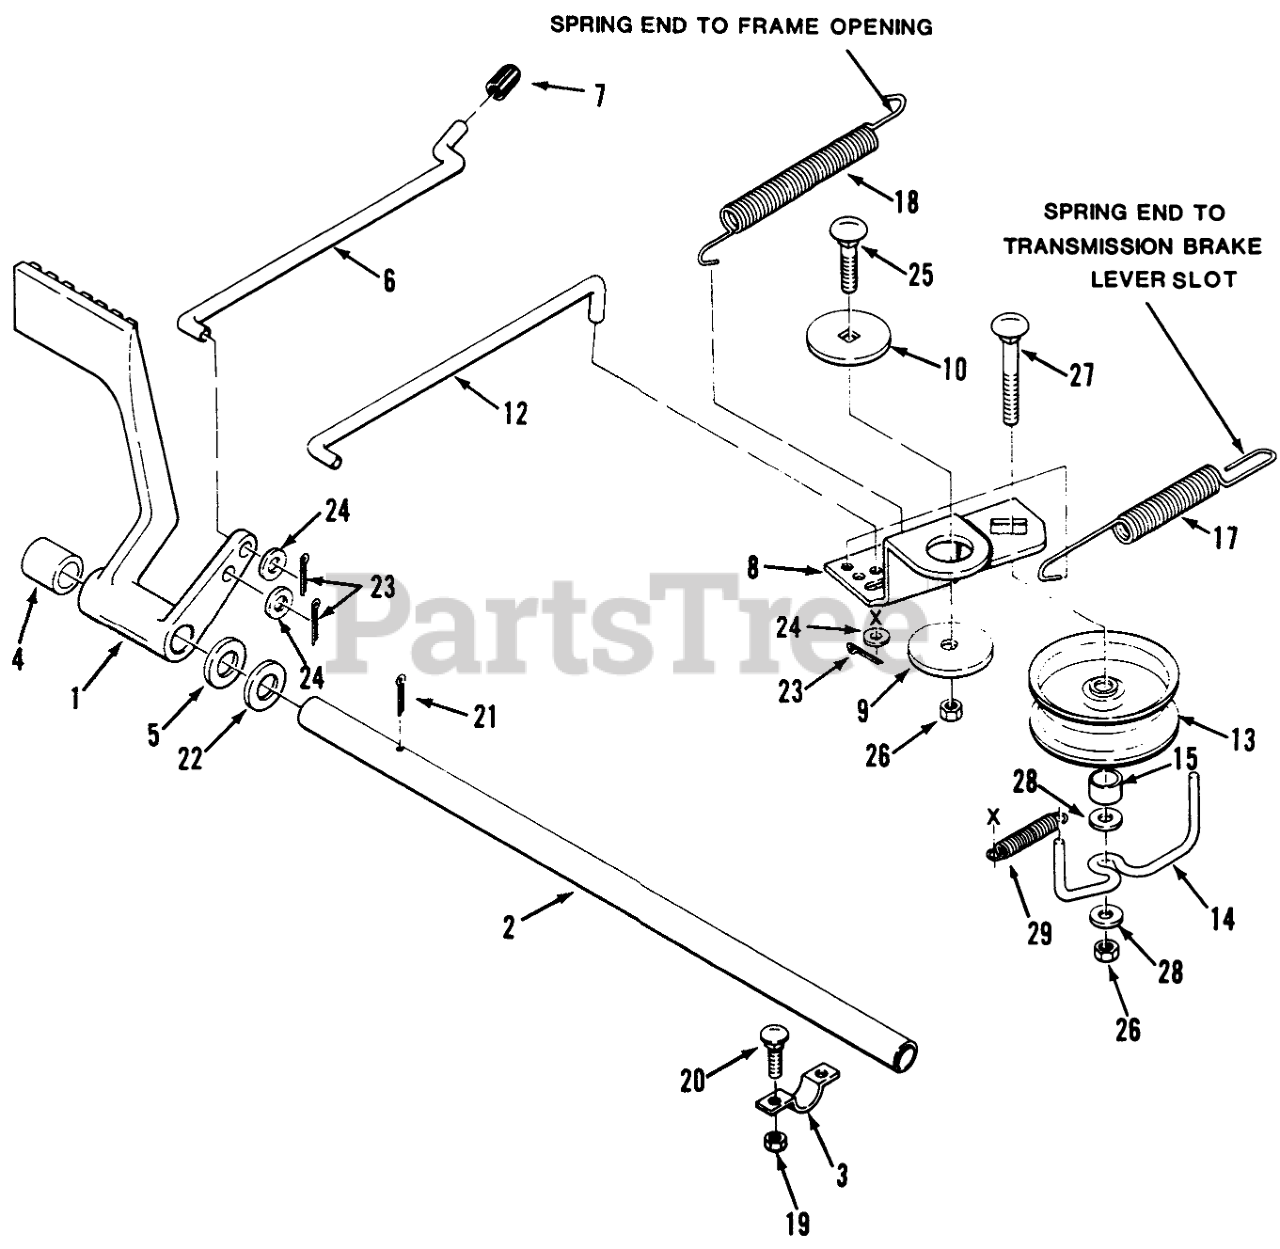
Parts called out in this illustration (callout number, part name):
1	PEDAL BRAKE R
2	SHAFT PEDAL
3	CLAMP
4	SPACER
5	WASHER-WAVE
6	Lock Rod
8	ARM-IDLER R
9	BUSHING
10	WASHER-BEARING
12	ROD-CLUTCH/BRAKE B
13	PULLEY IDLER
14	GUIDE-BELT
15	SPACER
17	SPRING - BRAKE
18	SPRING - CLUTCH
19	Nut
20	SCREW-CARR
21	PIN-COTTER
22	Washer
23	PIN-COTTER
24	WASHER-PLAIN
25	BOLT-CARR
26	NUT-LOCK, NI
27	SCREW-CARR
28	WASHER-FLAT
29	EXTENSION-SPRING
